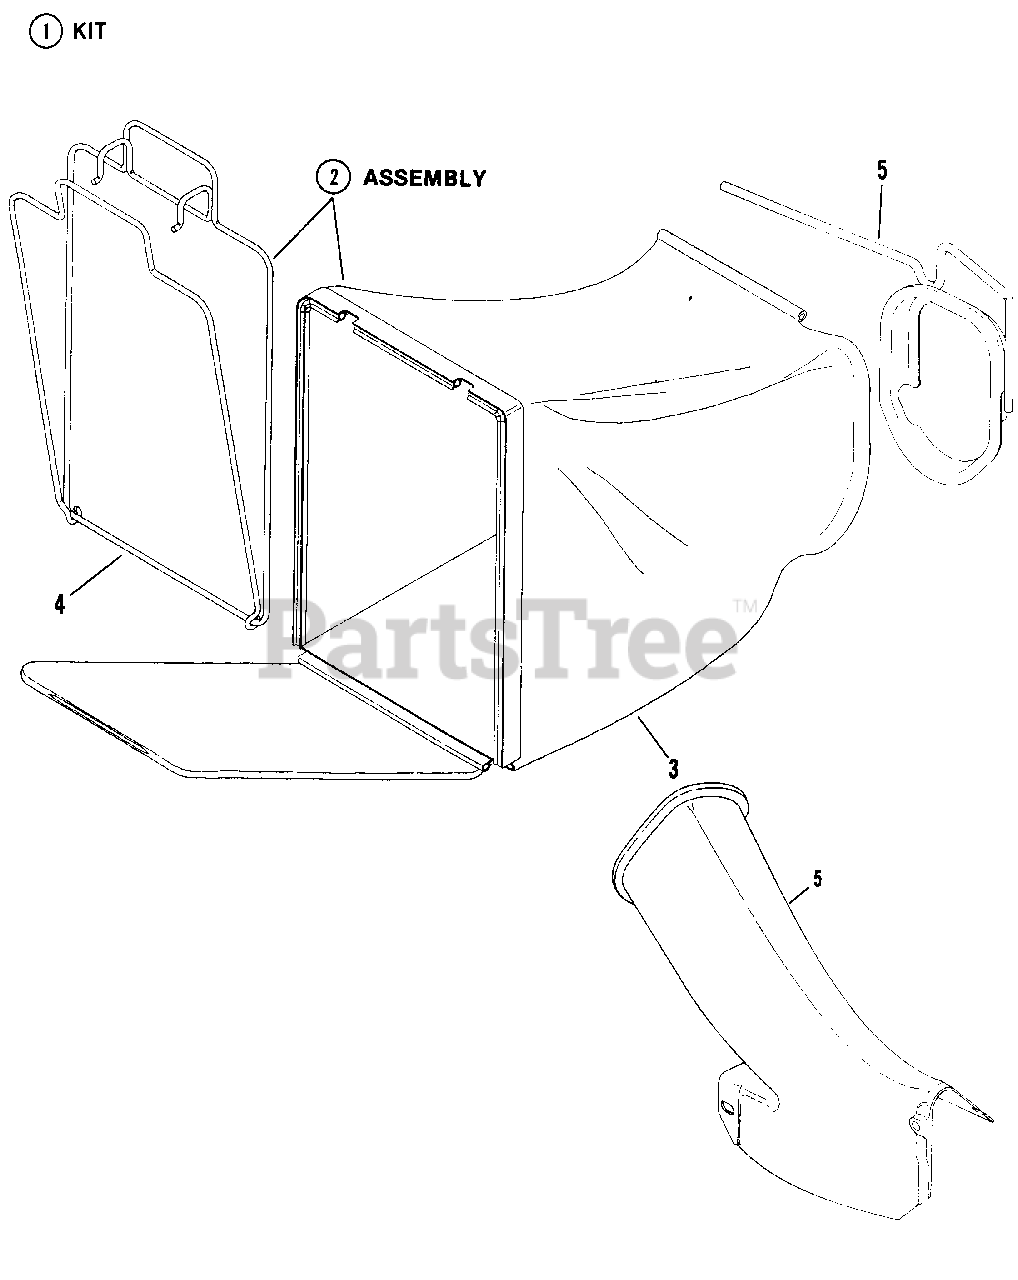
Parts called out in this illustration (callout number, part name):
1	KIT, KWIK-N-EZY Catcher
2	ASSEMBLY, Grass Bag
3	BAG, KWIK-N-EZY
4	ASSEMBLY, Bag Wire
5	CONNECTOR, Grass Bag
6	ADAPTER, Bag
